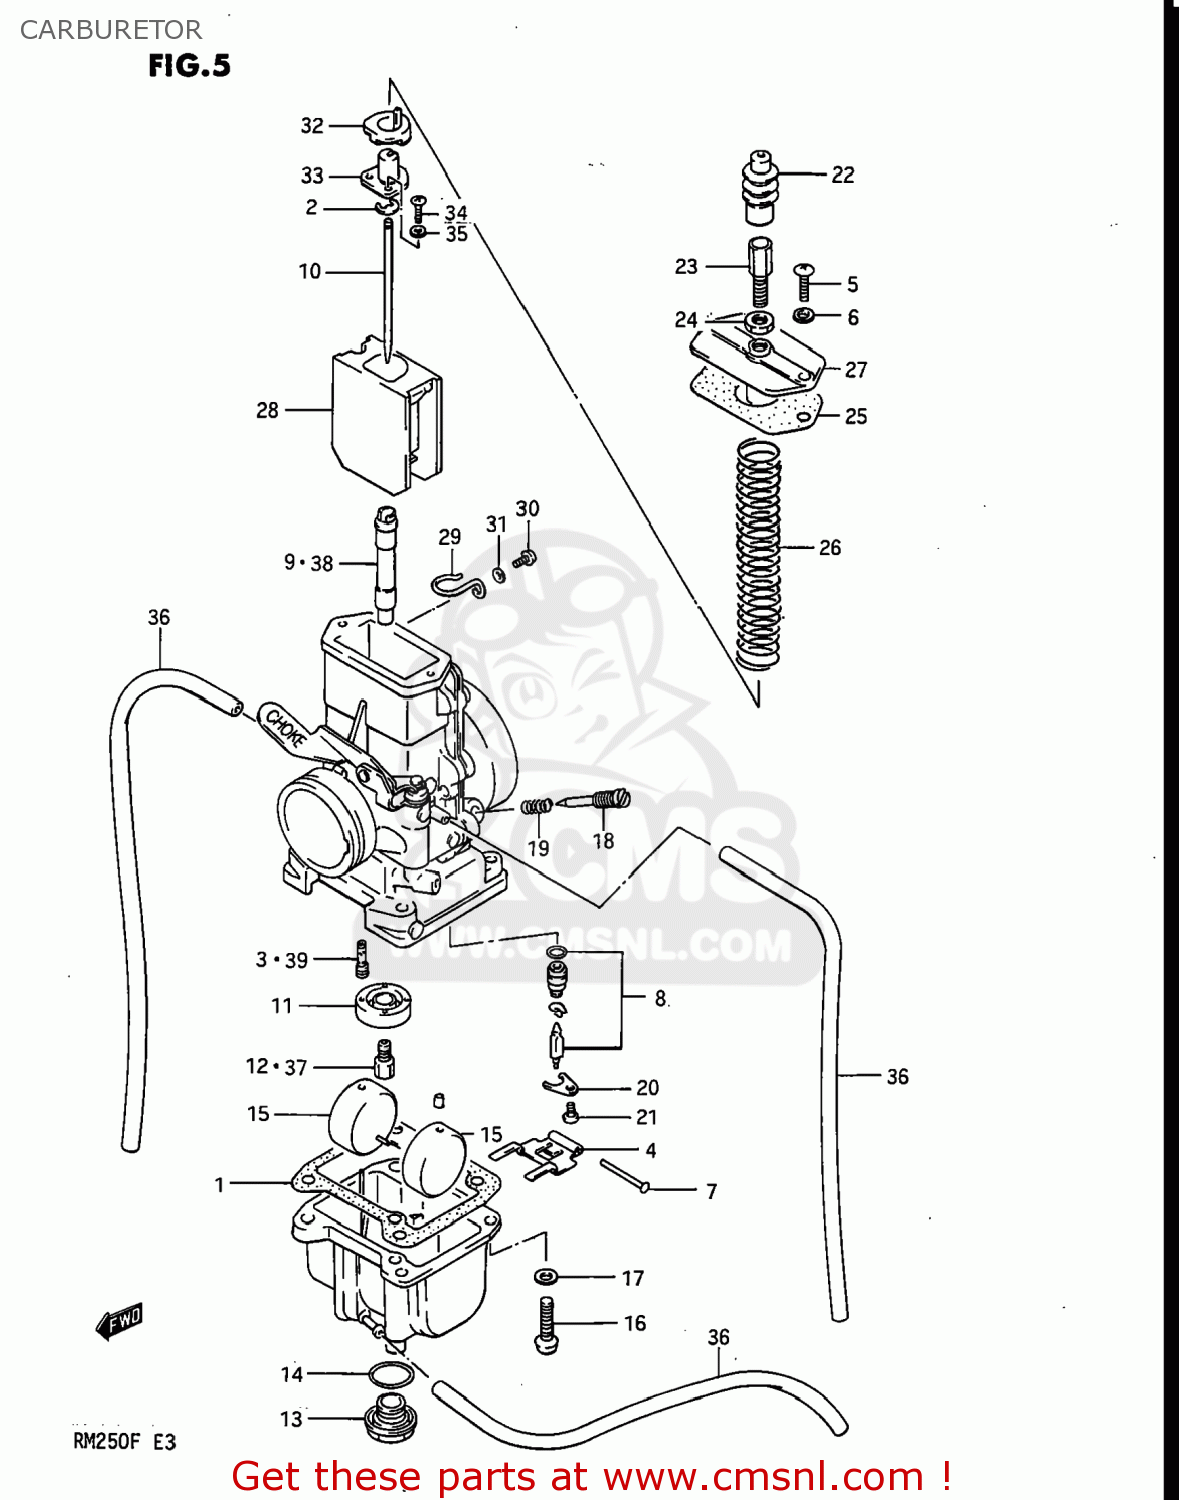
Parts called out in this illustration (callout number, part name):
1	GASKET,FLOAT CAHMBER (NAS)
2	CLIP
3	JET,PILOT(50)
4	ARM,FLOAT
5	SCREW
6	LOCK WASHER
7	PIN,FLOAT
8	VALVE ASSEMBLY,NEEDLE
9	JET,NEEDLE
10	NEEDLE,JET
11	RING,MAIN JET FIXING
12	JET,MAIN(320)
13	SCREW,GUIDE
14	O RING,DRAIN PLUG
15	FLOAT
16	SCREW 5X20
17	LOCK WASHER
18	SCREW,PILOT AIR
19	SPRING
20	PLATE
21	SCREW 4X6
22	CAP,CABLE ADJUSTER
23	ADJUSTER,CABLE
24	NUT
25	GASKET,MIXING CHAMBER (NAS)
26	SPRING,THROTTLE VALVE
27	CAP,CARBURETOR,TOP
28	VALVE,THROTTLE
29	CLIP
30	SCREW
31	LOCK WASHER
32	SEAT,RETURN SPRING
33	PLATE,NEEDLE JET
34	SCREW
35	LOCK WASHER
36	HOSE
37	JET,MAIN(300)
38	JET,NEEDLE
39	JET,PILOT
